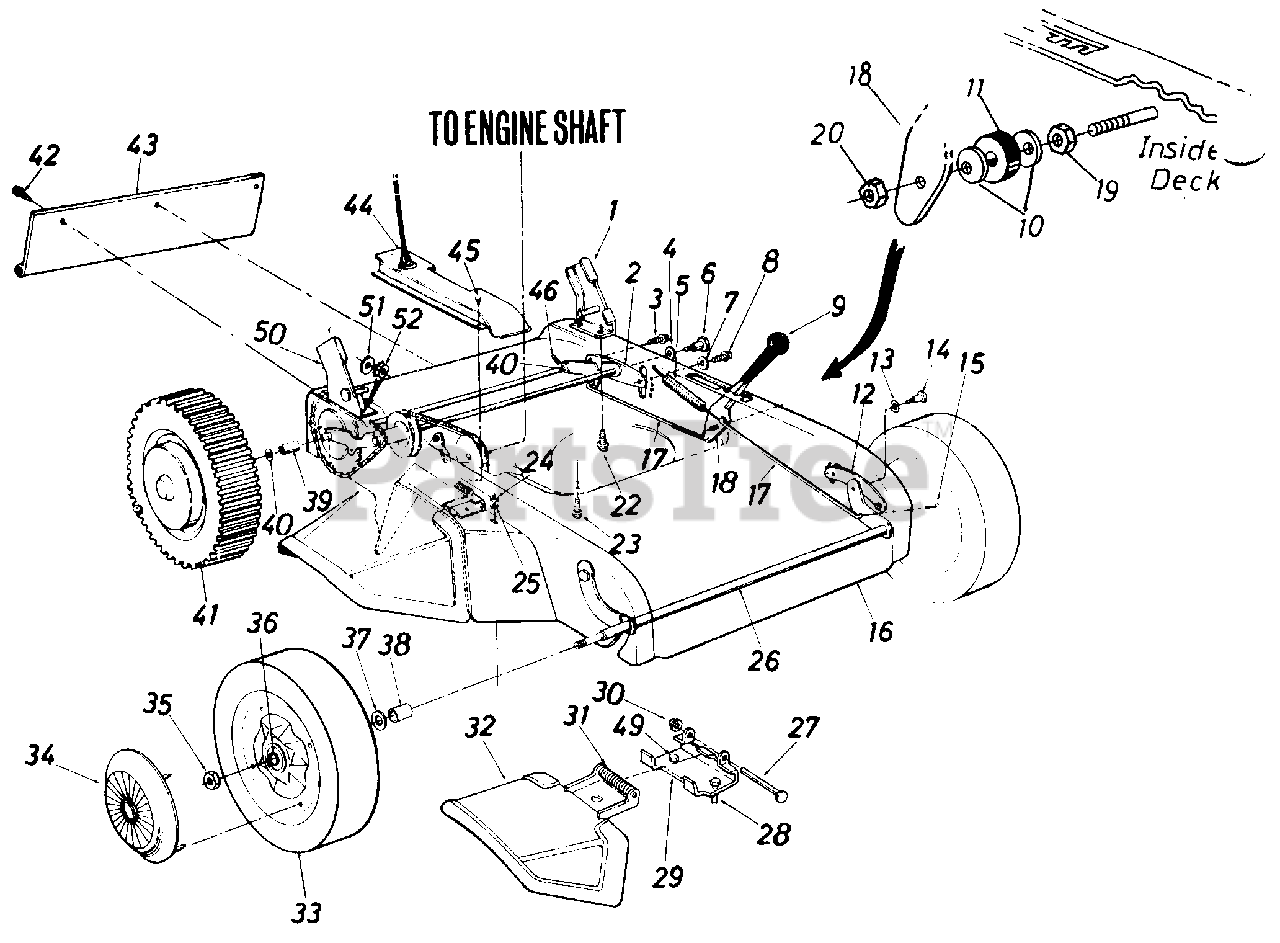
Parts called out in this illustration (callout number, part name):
1	Handle Mount Brkt. Ass'y - L.H.
2	Rear Pivot Brkt.
3	Hex Wash. Hd. TT-Tap Scr. 3/8-16 x 1" Lg.
4	Int. L-Wash. 3/8 I.D.
5	Extension Spring
6	Shld. Bolt .625 Dia. x .425
7	Belleville Washer
8	Hex Wash. Hd. TT-Tap Scr. 3/8-16 x 1" Lg.
9	Grip - Black
10	Belleville Washer
11	Rubber Washer
12	Front Pivot Brkt.
13	Int. L-Washer 3/8 I.D.
14	Shld. Bolt .625 Dia. x .425
15	Cotter Pin 3/32 x 3/4 Lg.
16	Upper Deck Ass'y.
17	Height Adj. Rod
18	Height Adj. Lever
19	Hex Jam Nut 3/8-24 Thd.
20	Hex L-Nut 3/8-24 Thd.
22	Hex Wash. Hd. B-Tap Scr. 5/16-18 x .5" Lg.
23	Hex Wash. Hd. TT-Tap Scr. 3/8-16 x 1" Lg.
24	Hex Nut 5/16-18 Thd.
25	L-Wash. 5/16" I.D.
26	Front Axle Ass'y.
27	Pivot Pin
28	Hex B-Tap Scr. 1/4 x .38 Lg.
29	Adapter Plate
30	Cap Speed Nut 1/4" Rod
31	Torsion Spring
32	Chute Deflector Ass'y. - Comp.
33	Wheel Ass'y. Comp. 8 x 1.75
34	Hub Cap - Front
35	Hex Ins. L-Nut 1/2-20 Thd.
36	Flanged Ball Brg. .500" I.D.
37	Fl-Wash. .531 I.D. x .93 O.D.
40	Fl-Wash. .531 I.D. x .93 O.D.
41	Wheel Ass'y. Comp. 8 x 1.75
42	Hex Bolt 1/4-20 x .75" Lg.
43	Rear Flap Ass'y.
44	Belt Guard
45	Hex Self-Tap Scr. #10 x .50"
46	Cotter Pin 1/8" Dia. x 1.0"
49	Hex Wash. Hd. AB-Tap Scr. 1/4 x .62" Lg.
50	Handle Mount Brkt. Ass'y. - R.H.
51	Fl-Wash. .281 I.D. x .73 O.D.
52	Sems Nut 1/4-20 Thd.
